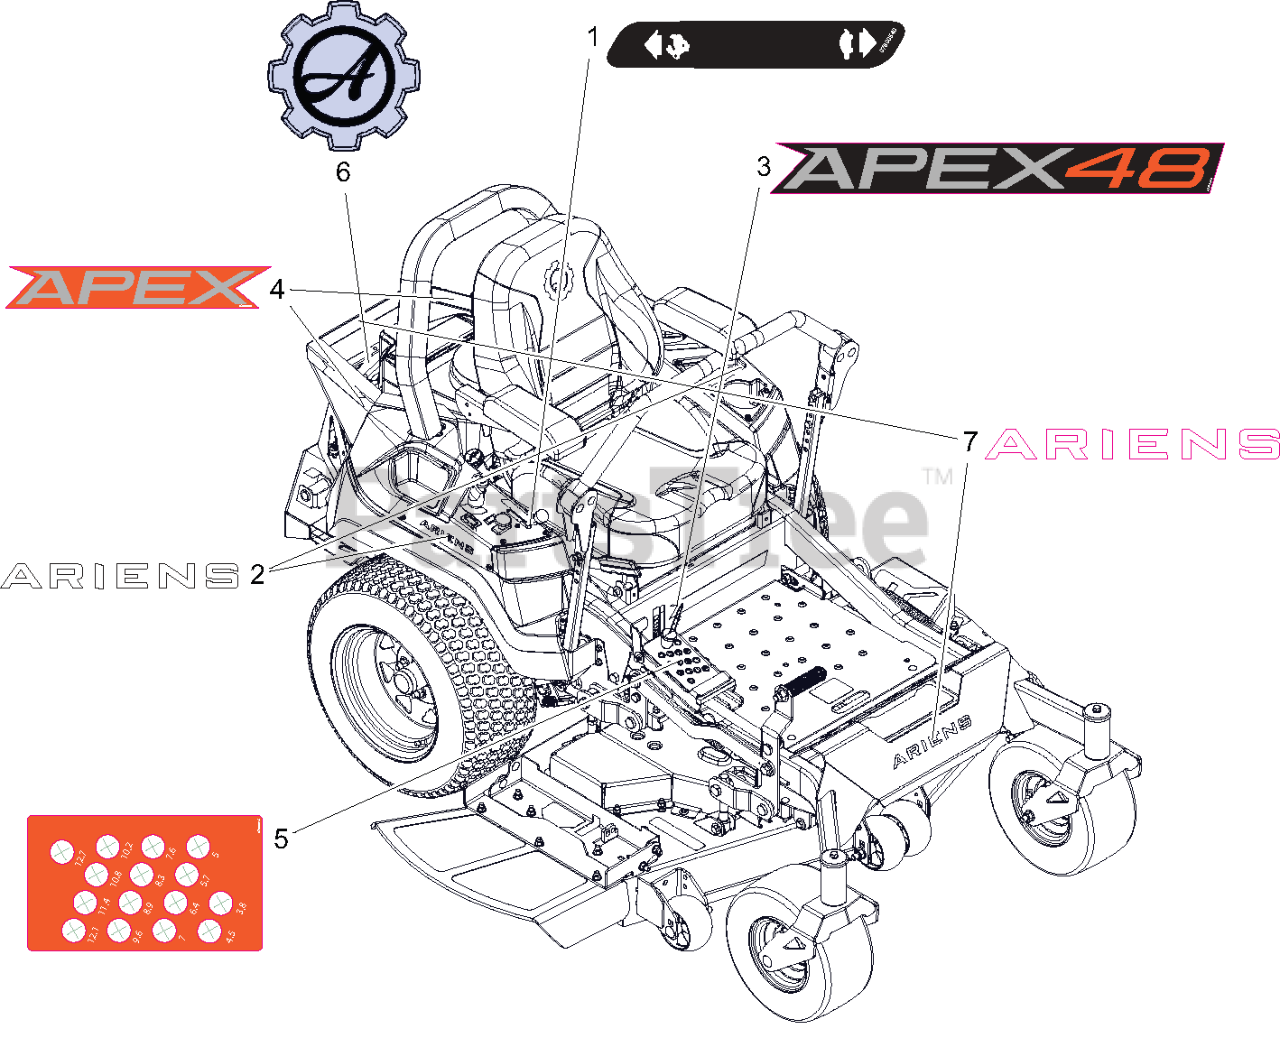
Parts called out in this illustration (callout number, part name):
1	DECAL, DASH DECAL
2	DECAL, ARIENS (6.50")
3	DECAL, 48" APEX KICKPLATE
4	DECAL, APEX FENDER
5	DECAL, APEX HOC METRIC
6	DECAL- ARIENS GEAR BADGE
7	DECAL - ARIENS 9.625"
